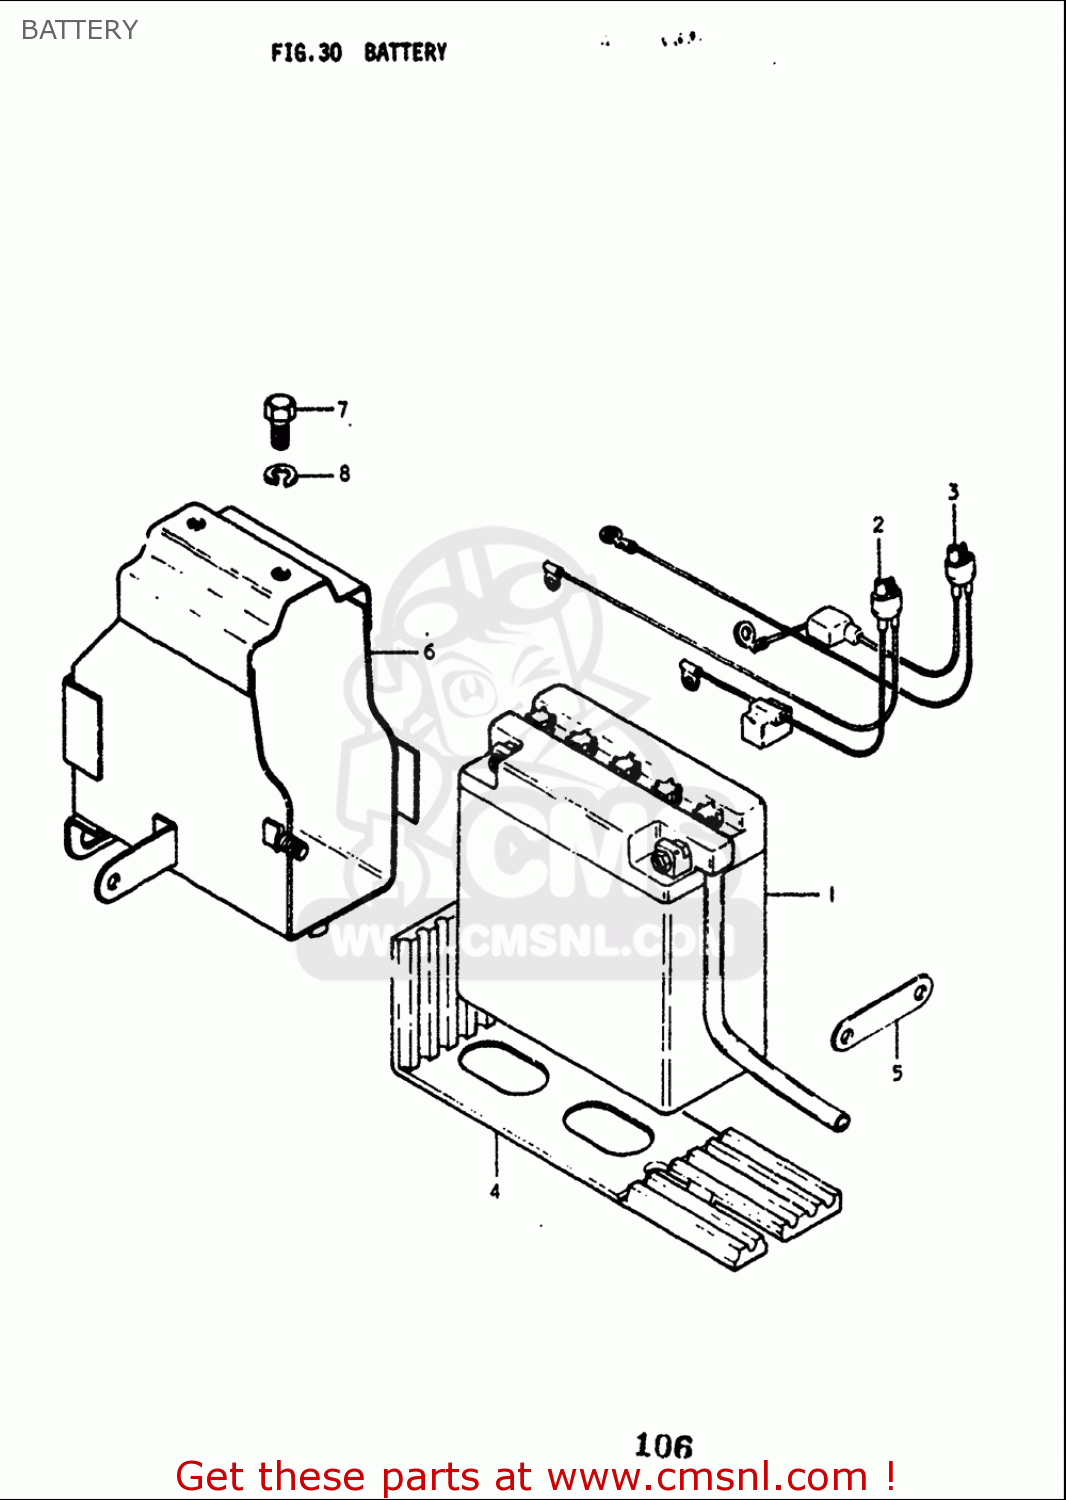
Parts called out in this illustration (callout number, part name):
1	BATTERY ASSY(YB5L-B,12V5.3AH)
3	LEAD WIRE
7	BOLT
8	WASHER,LOCK
